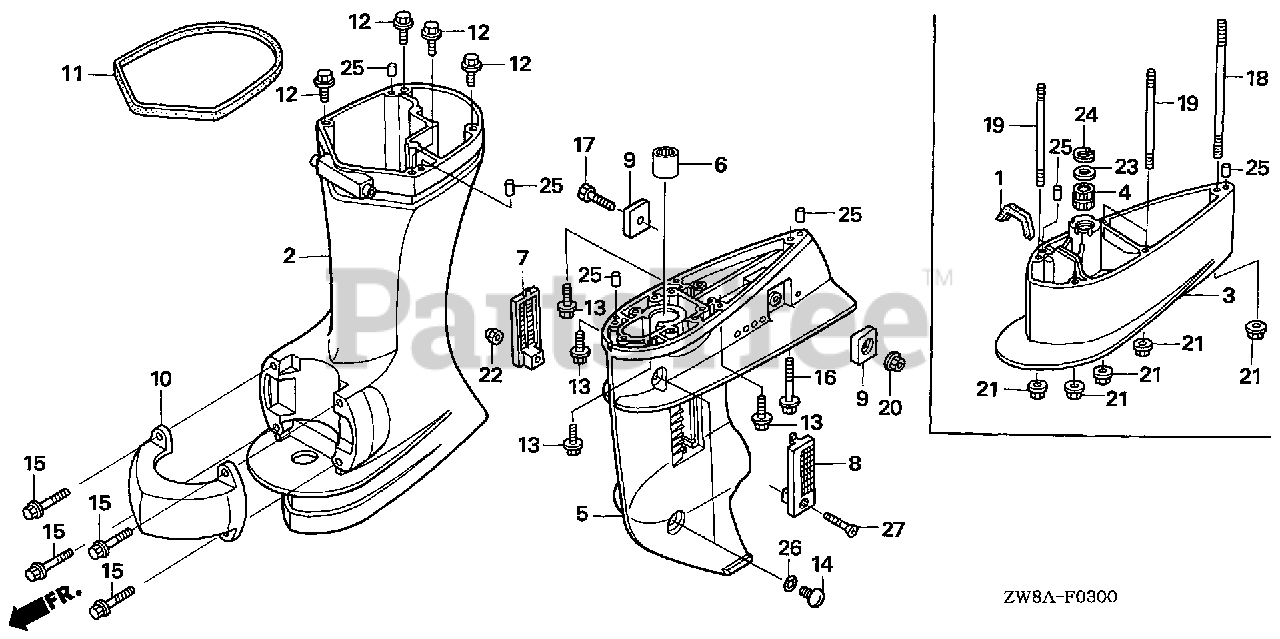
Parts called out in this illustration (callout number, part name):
1	GROMMET, WATER PUMP HOUSING
2	CASE, EXTENSION *NH282MU* (L) (OYSTER SILVER METALLIC-U)
3	SEPARATOR, EXTENSION *NH282MU* (UL) (OYSTER SILVER METALLIC-U)
4	BUSH, VERTICAL SHAFT
5	CASE, GEAR *NH282MU* (UL) (OYSTER SILVER METALLIC-U)
6	BEARING, NEEDLE (15X21X16)
7	SCREEN, R. WATER
8	SCREEN, L. WATER
9	METAL, ANODE
10	HOUSING, MOUNTING (LOWER) *NH282MU* (OYSTER SILVER METALLIC-U)
11	RUBBER, COVER (LOWER)
12	BOLT, FLANGE (8X35)
14	BOLT, OIL CHECK
15	BOLT, FLANGE (6X20)
17	BOLT, HEX. (6X25)
18	BOLT, STUD (6X211)
19	BOLT, STUD (6X162)
20	NUT, SELF-LOCK (6MM)
21	NUT, SELF-LOCK (6MM)
22	NUT, SELF-LOCK (5MM)
23	WASHER (20MM)
24	CIRCLIP (INNER) (30MM)
25	PIN, DOWEL (6X10)
26	O-RING (6.9X1.45)
26	O-RING (5.5X1.5)
27	SCREW, OVAL (5X28)
